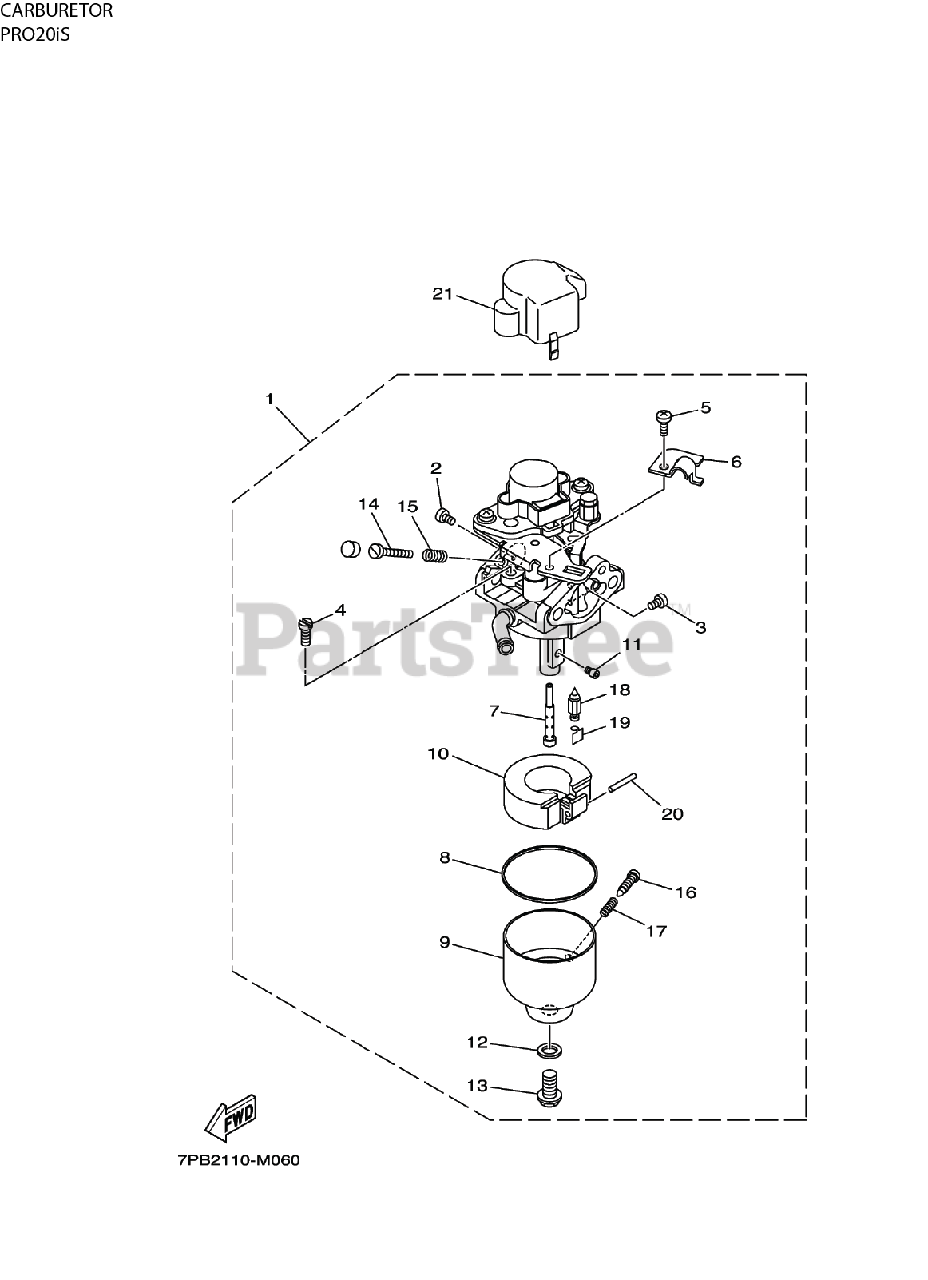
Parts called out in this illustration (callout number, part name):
1	CARBURETOR ASSEMBLY
2	SCREW - BOLT
3	SCREW - ROD
4	JET, MAIN (#37.5)
5	SCREW - PAN HEAD
7	SHIM, CAMSHAFT
9	BOWL, FUEL - BODY FLOAT CHAMBER 1
11	JET, MAIN (#67.5)
14	SCREW - PILOT ADJUSTING
16	SCREW - PLUG DRAIN
18	NEEDLE ASSEMBLY
20	PIN, FLOAT
21	COVER, AIR CLEANER - COVER 1
